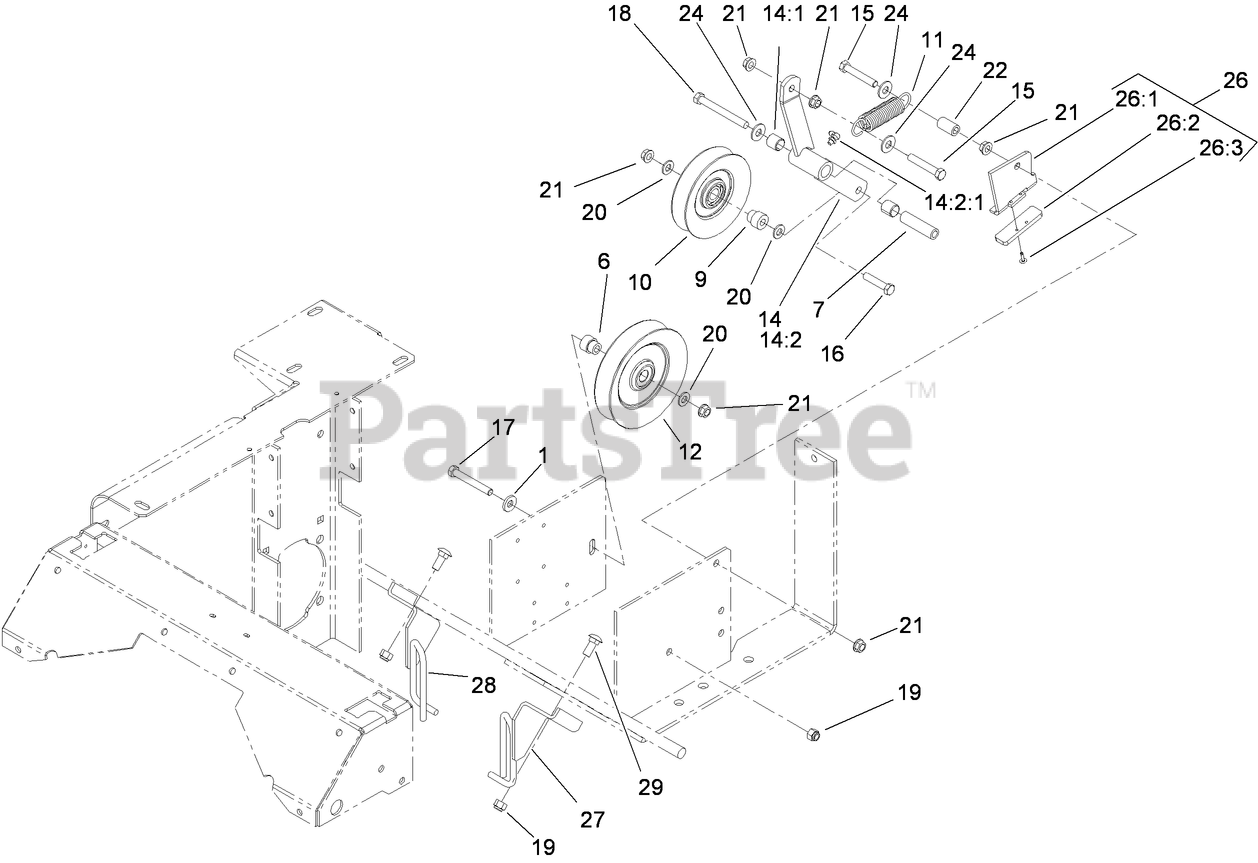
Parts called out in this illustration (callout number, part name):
1	WASHER-BELLEVILLE
6	Bushing-Idler
7	BUSHING-PIVOT, IDLER
9	BUSHING-IDLER
10	Idler
11	SPRING-EXTENSION
12	PULLEY-IDLER
14	Arm ASM
14:1	SLEEVE-BEARING
14:2	ARM-IDLER
14:2:1	FITTING-GREASE, 90 DEG
15	SCREW-HH
16	SCREW-HH
17	SCREW-HH
18	SCREW-HH
19	NUT-LOCK, NI
20	WASHER-FLAT
21	NUT-HHF, WHIZ
22	SPACER
24	WASHER-FLAT
26	Travel Limiter ASM
26:1	Plate-Limiter, Pulley
26:2	PAD-BUMPER
26:3	RIVET
27	GUIDE-BELT, LH
28	GUIDE-BELT, RH
29	BOLT-CARR
